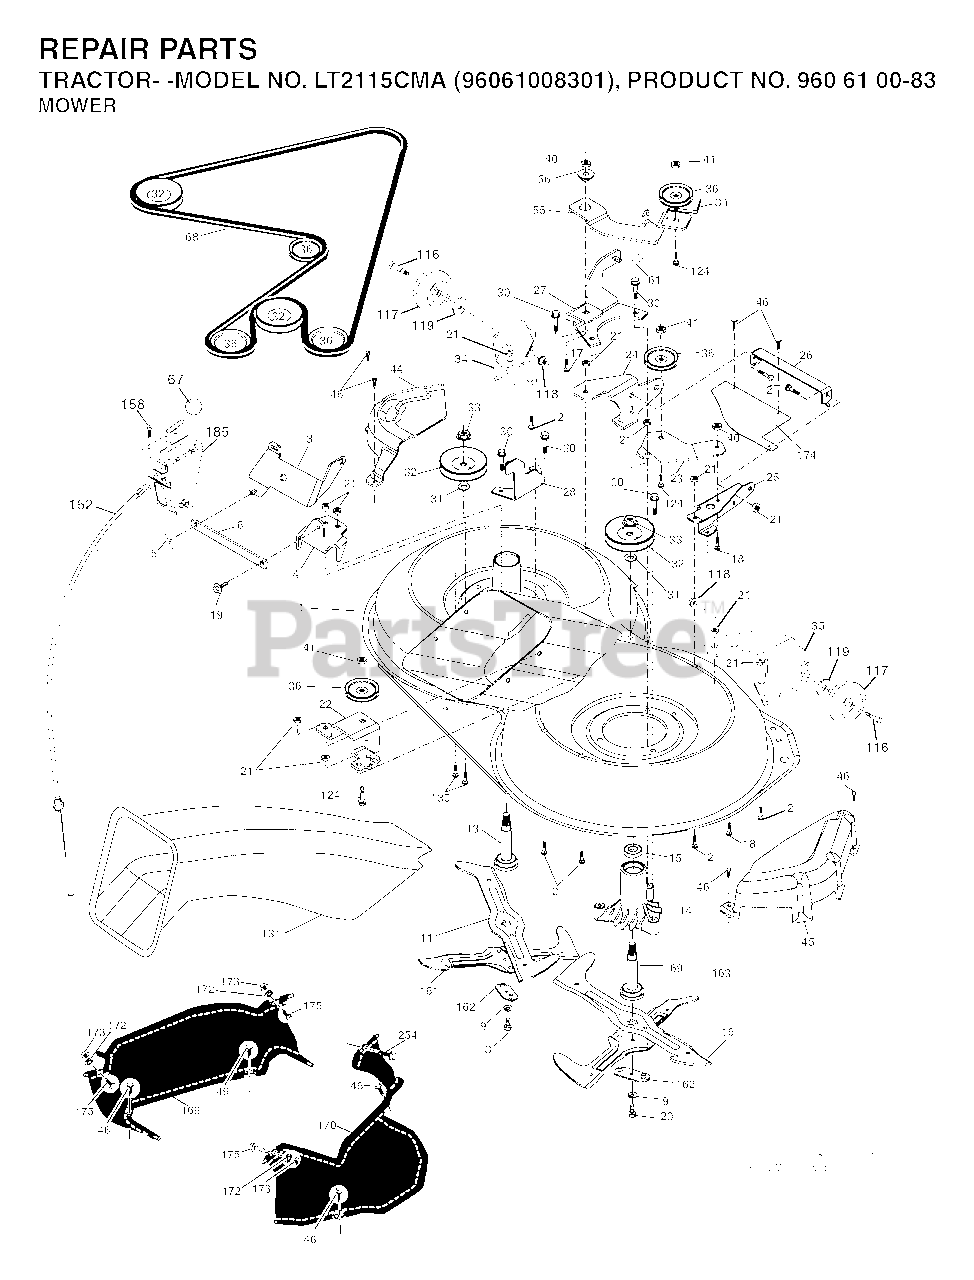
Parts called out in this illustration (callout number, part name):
2	BOLT
3	BRACKET
5	RETAINER-SPRNG RB
6	BAR SWAY
9	LOCKWASHER
13	SHAFT ASM VENT
14	HSG MANDREL
17	BOLT.3/8-14X1.25
19	BOLT SHD 5/16-18
21	LOCKNUT
24	BRACKET
25	BRACKET
28	BRACKET
30	SCREW, WASHER HEAD
31	WASHER.SPACER.MANDREL
33	NUT.FLANGE.LOCK.TOP
36	PULLEY.IDLER.4.25
40	LOCKNUT
41	NUT LOCK FLG 3/8-16 UNC
45	MANDREL COVER
46	SCREW.1/4-20X5/8
56	SPACER.RETAINER.MOWER
61	SPRING.TENSION.BELT
67	KNOB T (3/8 HOLE)
69	SHAFT.ASM.W/LWR.BRG.RH.THREAD
84	KEEPER, BELT IDLER
116	BOLT.SHOULDER.3/8-16X3-5/8
117	WHEEL. GUAGE RALLY
118	LOCKNUT
119	WASHER
124	BOLT.3/8-16X1.50
131	CHUTE BAGGER
158	SCREW
169	COVER TERMINAL BATTERY
172	PUSH.NUT.ROUND.3/8.DIAM
173	NUT
185	HEAD ASM. CABLE CLUTCH
254	SCREW 3/8-16X1
